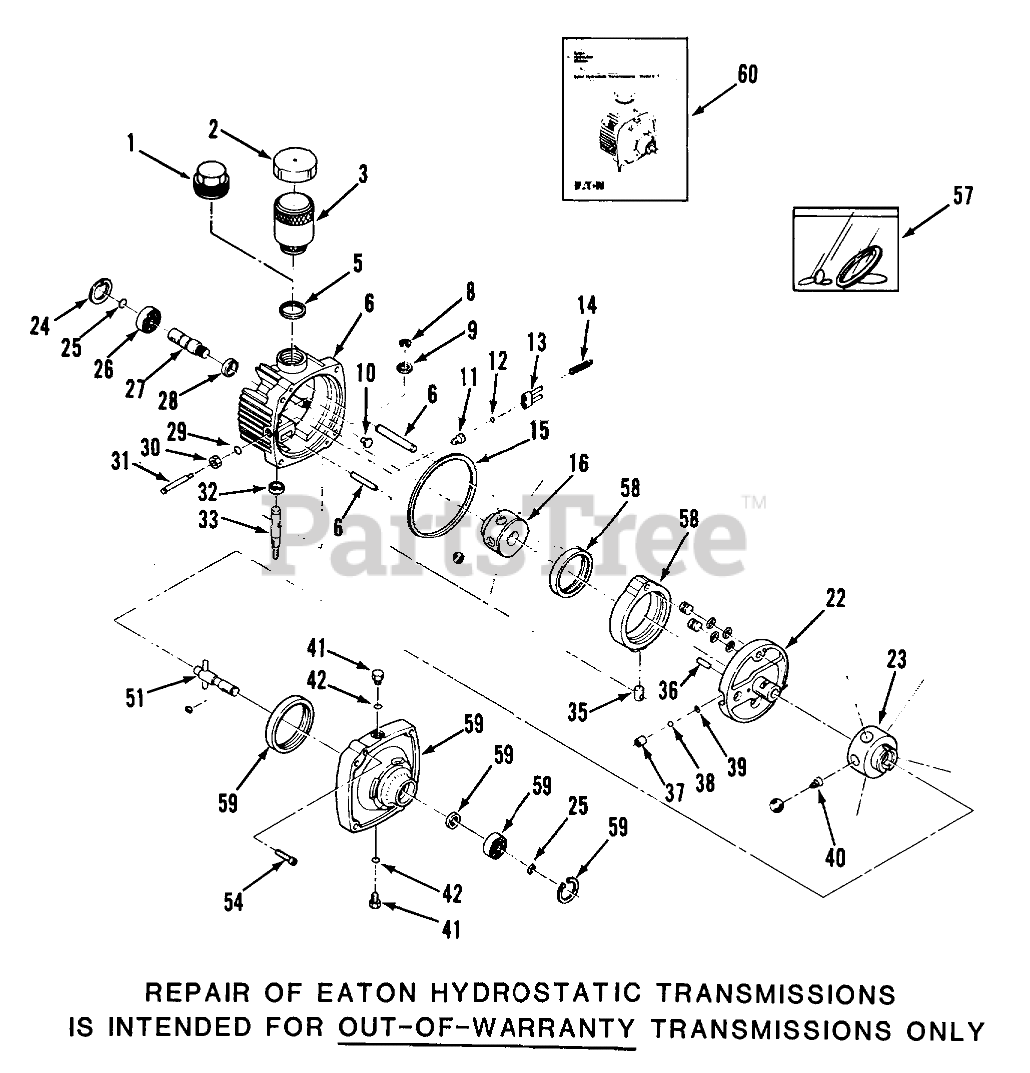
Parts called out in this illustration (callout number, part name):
2	RESERVOIR COVER
3	BODY-RESERVOIR
5	Square Cut Seal Ring (included in item 57)
6	Cover Service Kit (includes Pivot Pin Dowel, Control Shaft Dowel, & items 8, 9, 28, 32 & 33).
8	External Retaining Ring (included in item 6)
9	Control Shaft Washer (included in item 6)
10	Button
11	SUB-ASS'Y O-RING
12	Dump Valve Bracket "O" Ring (included in item 11 & 57)
13	SUB-ASS'Y BRACKET
14	SPRING-VALVE
15	Square Cut Seal Ring (included in item 57)
16	SUB-ASS'Y PUMP ROTOR
22	Pintie Subassembly-Used in CCW rotation trans. Model No. 00700-023 (includes Piston, Backup Ring, "O" Ring, & items 36, 37, 38 & 39)
23	SUB-ASS'Y MOTOR
24	Retaining Ring
25	SNAP-RING
26	BEARING-BALL (INPUT)
27	SHAFT-INPUT
28	Oil Seal (included in item 6 & 57)
29	Dump Valve "O" Ring (included in item 57)
30	Nut-Gasket Subassembly (included in item 57)
31	SHAFT-DUMP VALVE
32	Oil Seal (included in item 6 & 57)
33	Control Shaft Kit (included in item 6)
35	INSERT-CAM RING
36	Coil Pin (included in item 22)
37	Check Valve Body (included in item 22)
38	Grade 200 Ball 5/16 O.D. (included in item 22)
39	Retaining Ring (included in item 22)
40	Piston Spring (included in item 23)
41	"O" Ring Plug Subassembly (includes item 42)
42	Tube Fitting "0" Ring (included in item 41 & 57)
51	Output Shaft Subassembly (included in item 59)
54	Screw
57	Overhaul Sealing Kit (includes Dampening Piston "O" Rings, Dampening Piston Backup Rings, Output Shaft Oil Seal, Plug "O" Ring & items 5, 11 w/12, 15, 28, 29, 30, 32 & 42)
58	Cam Ring Subassembly (includes Pump Race & Cam Ring)
59	Body Subassembly (includes Body, Oil Seal, Output Ball Bearing, Snap Ring, Retaining Ring, Motor Race & item 51)
60	Hydrostatic Transmission Repair Manual
